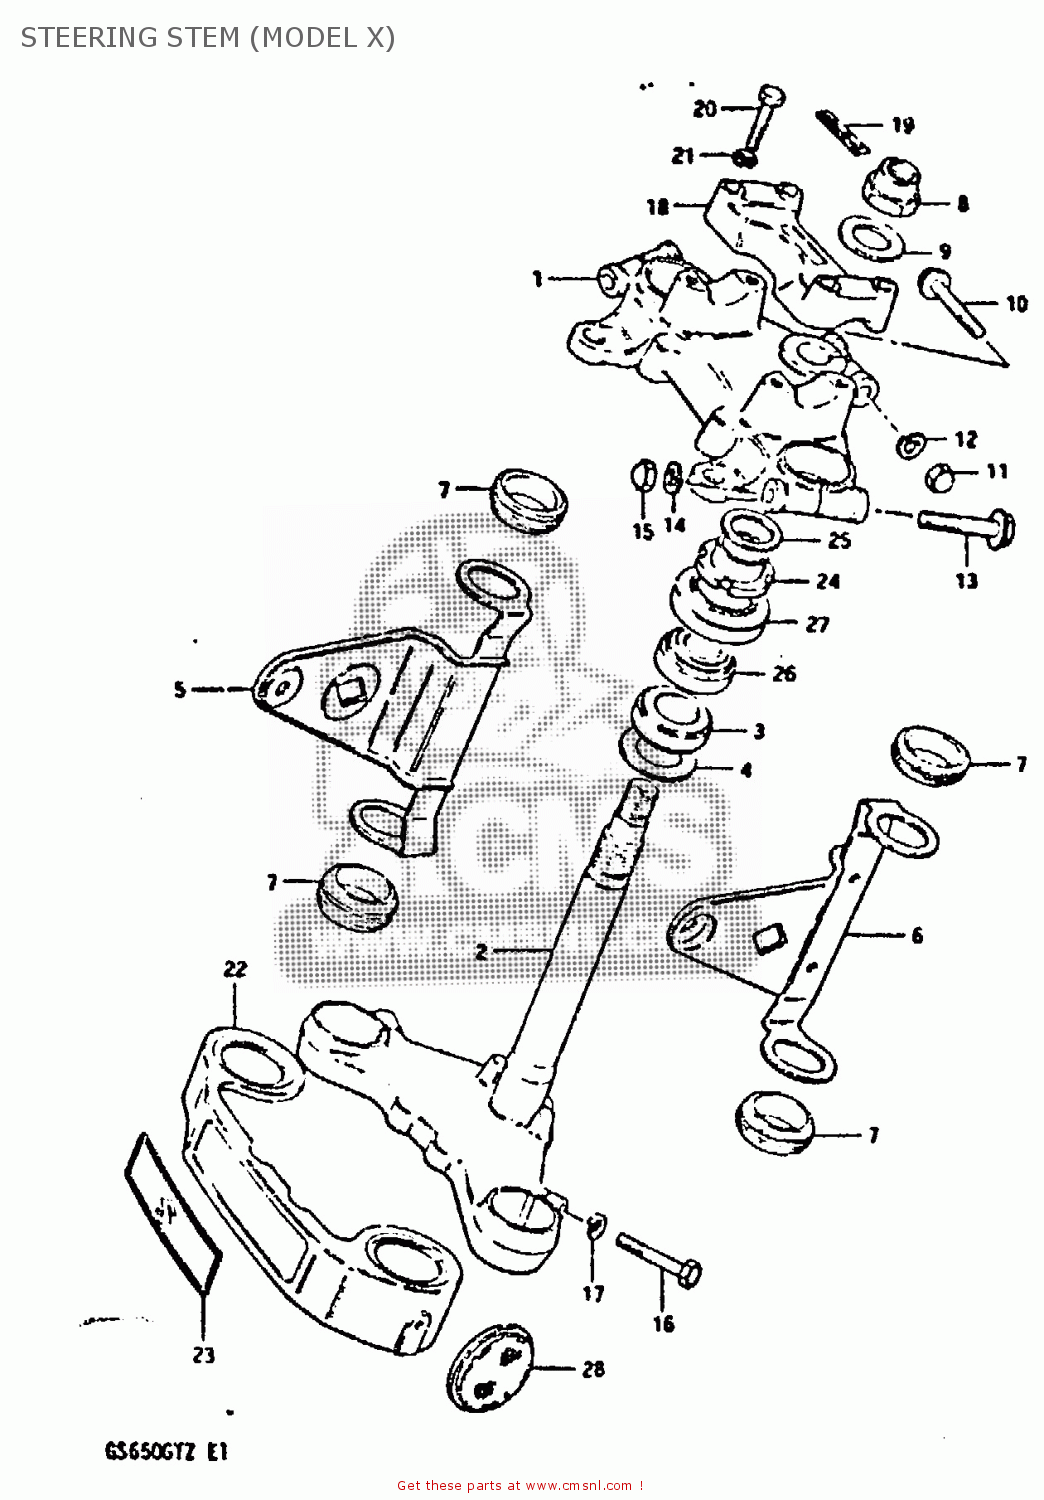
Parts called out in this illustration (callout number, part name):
1	STEM HEAD, STEERING (BLACK)
2	STEM, STEERING
3	BEARING
4	WASHER,THRUST
5	BRACKET,HEADLAMP,RIGHT
6	BRACKET,HEADLAMP,LEFT
7	CUSHION,HEADLAMP BRACKET
8	NUT,FR FORK UPR BRACKET
9	WASHER
10	BOLT
11	NUT,M8X1.25X12
12	LOCK WASHER
13	BOLT 10X55
14	LOCK WASHER
15	NUT
16	BOLT 10X40
17	LOCK WASHER
18	HOLDER,HANDLEBAR
19	EMBLEM,HANDLE CLAMP
20	BOLT
21	LOCK WASHER
22	COVER,FRONT FORK
23	EMBLEM
24	NUT,STEERING STEM
25	WASHER(18.5X24X1)
26	TAPER,ROLLER BEARING
27	DUST SEAL,STEERING,UPPER
28	REFLEX REFLECTOR,RR
